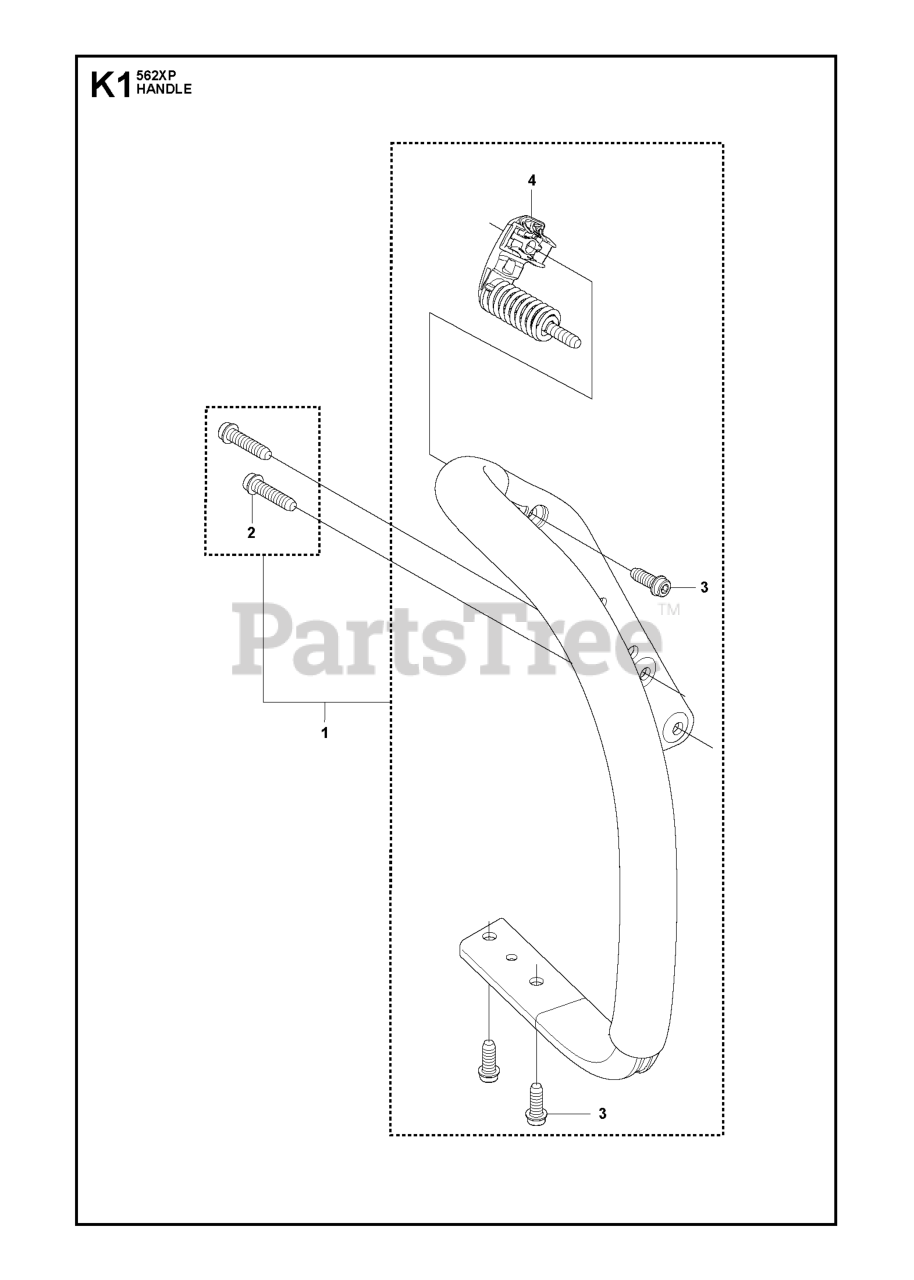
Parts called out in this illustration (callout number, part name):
1	FRONT HANDLE
2	SCREW
3	SCREW IHSCFT
4	ANTIVIBRATION ELEMENT
